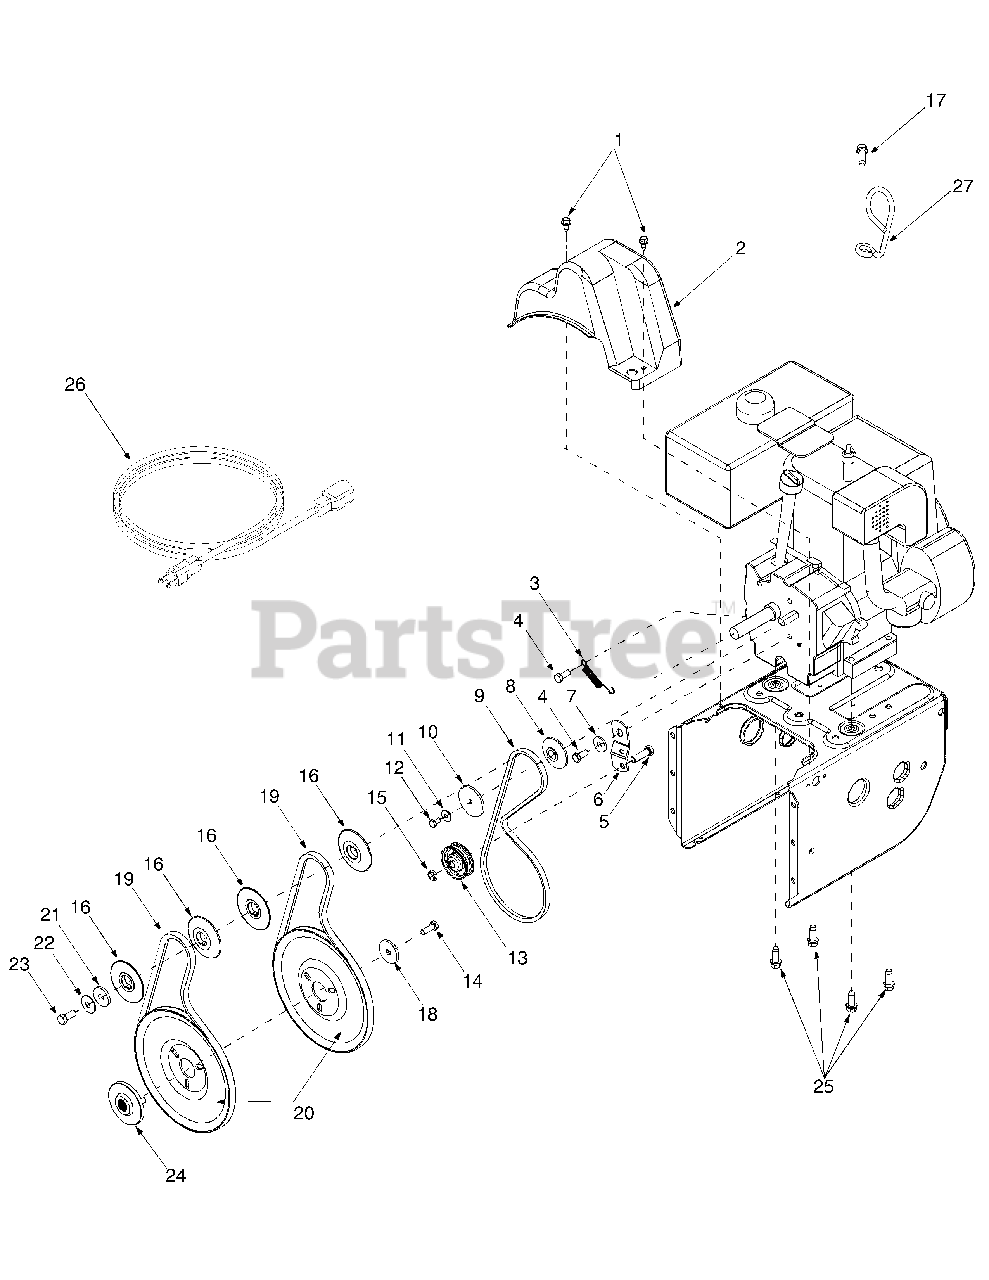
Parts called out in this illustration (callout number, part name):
1	Hex Washer Screw 1/4-20 x.625
2	Belt Cover
3	Extension Spring
4	Hex Screw 5/16-24 x.75
5	Hex Cap Screw 3/8-16 x 1.25
8	Pulley Half
9	V-Belt
10	Pulley Half
11	Bell Washer
12	Hex Cap Screw 1/4-28 x.50
13	Flat Idler
14	Lock Hex Cap Screw 5/16-24
15	Lock Jam Nut 3/8-16
16	Pulley Half
17	Self Tapping Screw, 5/16-18 x 1.00
18	Flat Washer
19	Belt
20	Auger Pulley
21	Flat Washer 3/8 x 1.25 OD
22	Bell Washer
23	Hex Cap Screw 3/8-24
24	Adapter Pulley
25	Hex Screw 3/8-16 x 1.0
26	Extension Cord
27	Cable Control Wire
